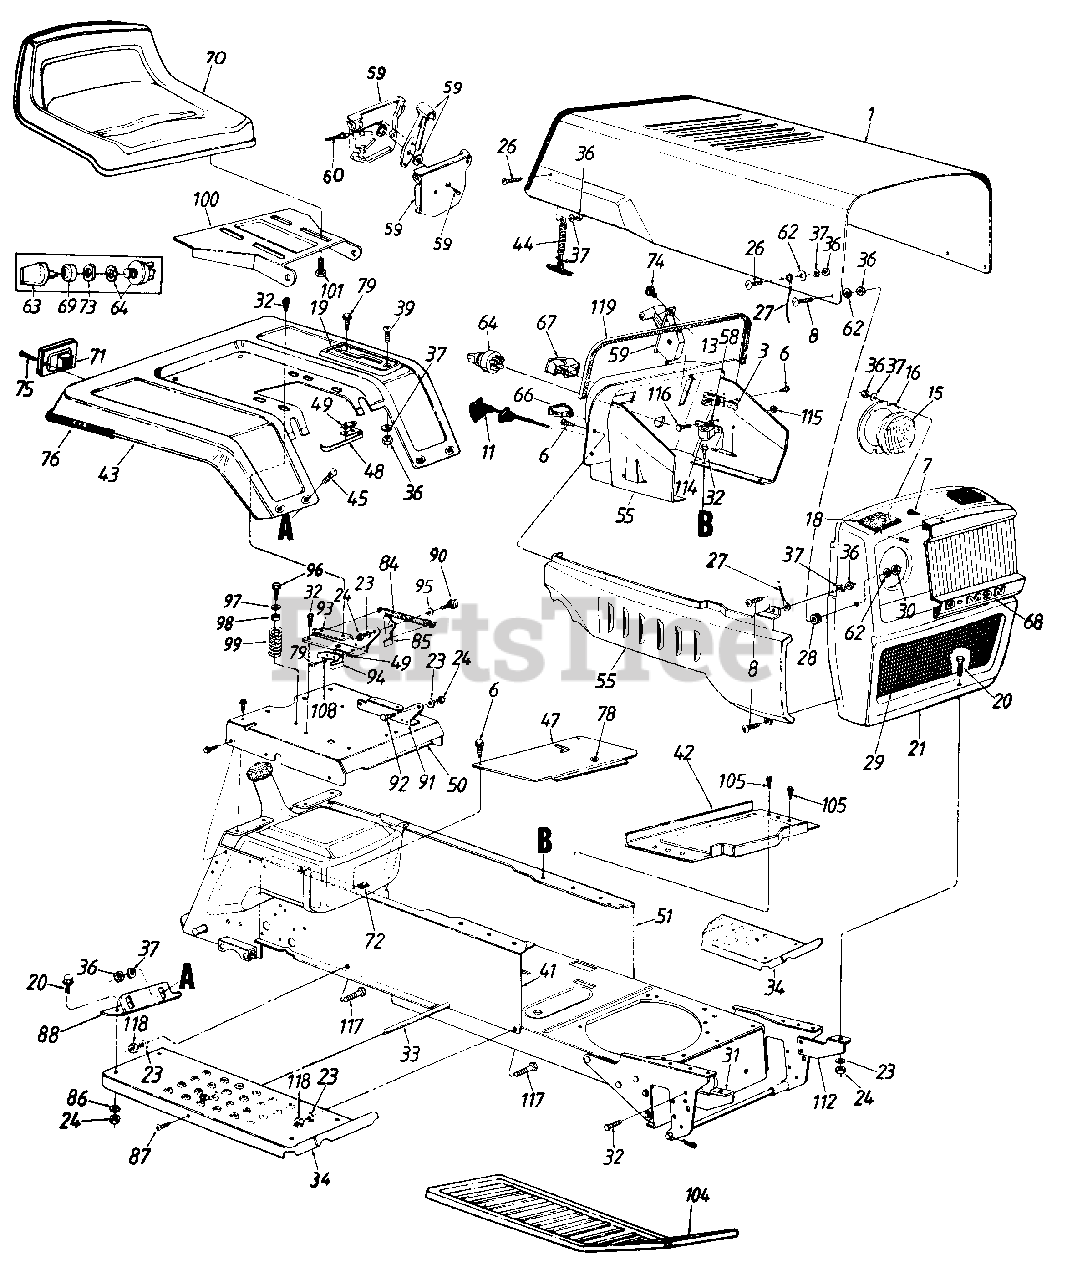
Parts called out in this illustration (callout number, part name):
6	Truss Mach. B-Tap Scr. #10 x .5" Lg.
7	Hex Wash Hd. AB-Tap Scr. #8 x .5" Lg.
8	Truss Mach. Scr.
11	Choke Control
13	Circuit Breaker
15	Headlight
16	Headlight Retainer
18	Foam Strip
19	Speed Control Index Brkt.
20	Hex Bolt 5/16-18 x .75" Lg.
21	Grille
23	L-Wash. 5/16" I.D.
24	Hex Nut 5/16-18 Thd.
26	Truss Mach. Scr. 1/4-20 x .5" Lg.
27	Hood Stop
28	Rubber Washer
29	Grille Insert
30	Hex Patch L-Nut 1/4-20 Thd.
31	Grille Mtg. Brkt. R.H.
32	Hex Wash. Hd. AB-Tap Scr. 5/16 x .75" Lg.
33	Running Board Rod
37	L-Wash. 1/4" I.D.
39	Truss Mach. Scr. 1/4-20 x .62" Lg.
41	R.H. Side Frame
42	Battery Carrier
43	629 Rear Fender
44	Hood Latch Ass'y.
45	Carriage Bolt 1/4-20 x .50" Lg.
47	Transmission Panel
48	Reverse Safety Switch
49	Insulator Nut Plate
50	Seat Plate
51	L.H. Side Frame
55	Side Cover R.H.
58	Ext. L-Wash. 1/4" I.D.
59	Throttle Control Box Ass'y.
60	Throttle Control Wire 35" Lg.
62	Fl-Wash. .281" I.D. x .73" O.D.
63	Ignition Key
64	Ignition Switch
66	Light Switch
67	Ammeter
68	Headlight Bezel
69	Ignition Switch Cap
70	Seat Ass'y.
71	Taillight Ass'y.
72	Speed Nut #10Z
73	Ignition Switch Nut
74	Truss Mach. AB-Tap Scr. #10 x .5" Lg.
75	Truss Hd. AB-Tap Scr. #6 x .62" Lg.
76	Trim Strip 81"
78	Snap Bushing
79	Hex Wash. Hd. AB-Tap Scr. #8 x .50" Lg.
84	Ext. Spring 5.31" Lg.
85	Seat Lift Brkt.
86	Bell-Wash. .345" I.D. x .88" O.D.
87	Truss Machine Scr. 5/16-18 x .75" Lg.
91	Seat Pivot Brkt. Support L.H.
92	Shld. Bolt .437" Dia. x .162"
93	Seat Pivot Brkt. Support R.H.
94	Spring Switch
95	Spr.-Wash...445" I.D.
96	Hex Wash. Hd. Tap Scr. 5/16-18 x .75" Lg.
97	Fl-Wash....344" I.D.
98	Bushing
99	Compression Spring
100	Seat Pivot Bracket
101	Hex Tap Scr. 3/8-16 x .75"
104	Foot Pad
105	Hex Tap Scr. 1/4-20 x .5" Lg.
108	Fiber Washer
112	Grille Mtg. Brkt. L.H.
114	Solenoid
115	Hex Sems Nut 1/4-20 Thd.
116	Hex Bolt 1/4-20 x .5" Lg.
117	Rib Neck Bolt 5/16-24 x .75" Lg.
118	Hex Nut 5/16-24 Thd.
119	Trim Strip 29" Lg.
